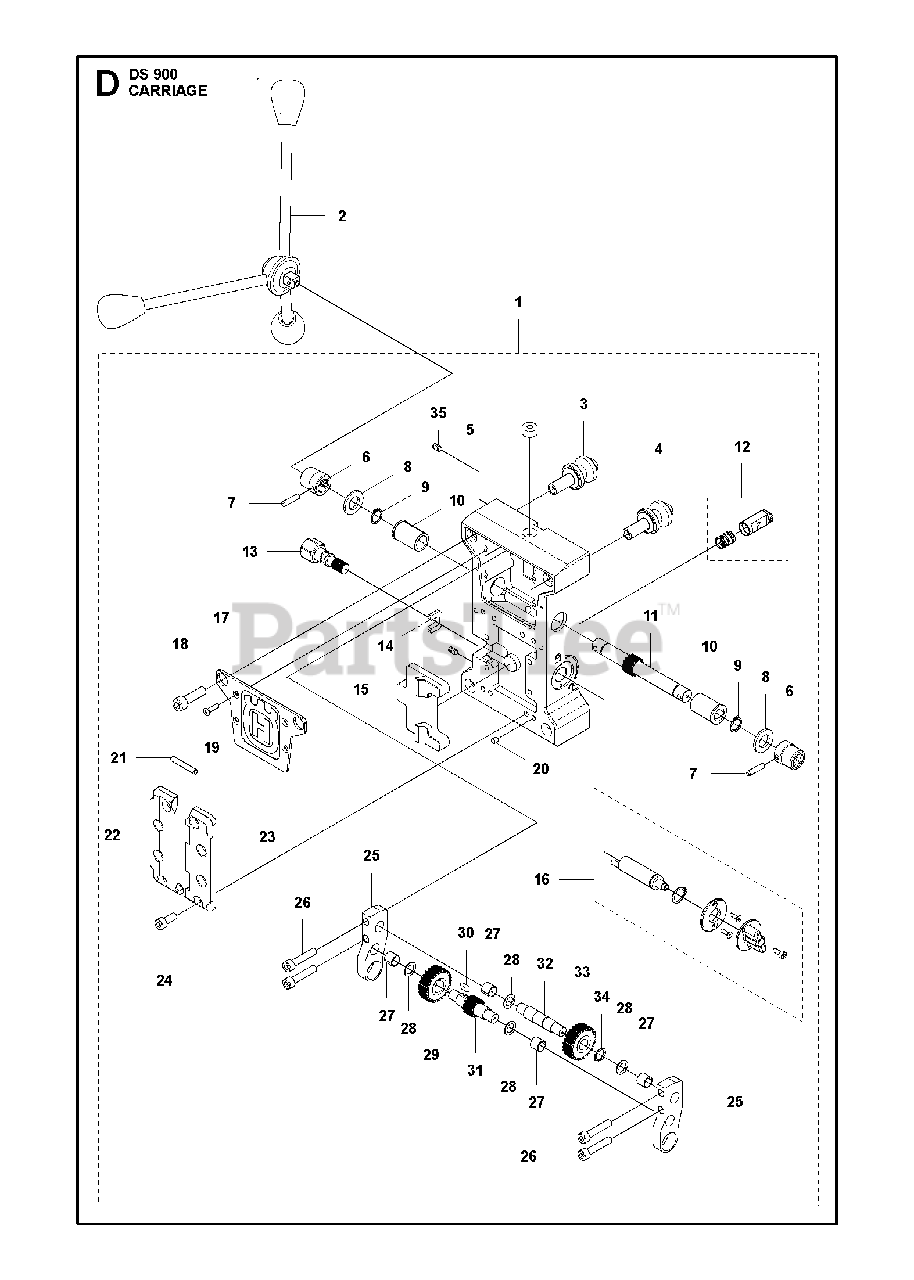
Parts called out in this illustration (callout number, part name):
3	WHEEL KITScrew included
4	WHEEL KITScrew included
7	PARALLEL PIN
9	CIRCLIP
20	PARALLEL PIN
